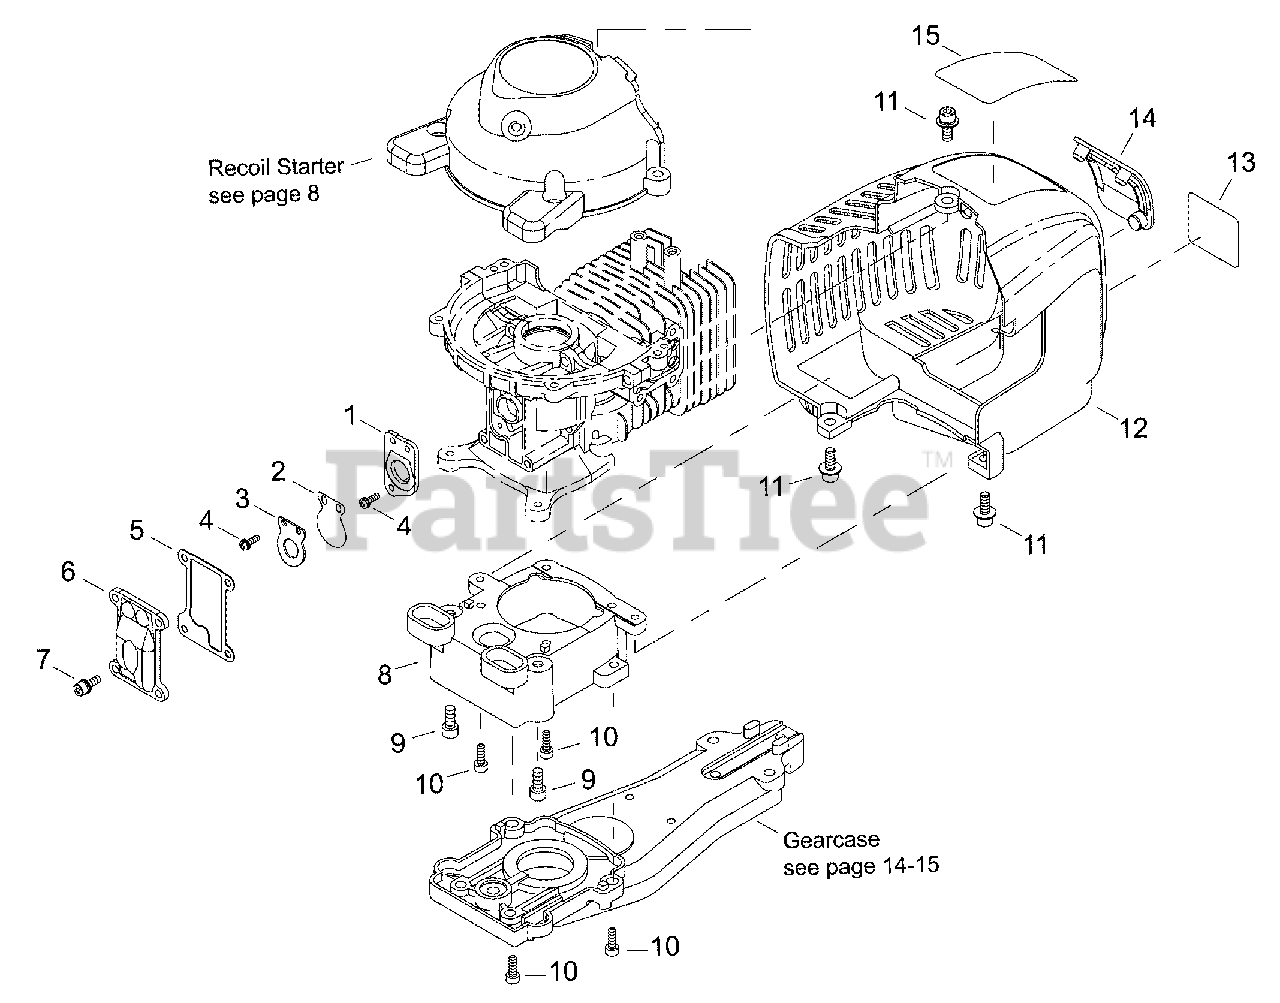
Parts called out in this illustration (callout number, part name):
1	PLATE, REED BACKING
2	VALVE, REED
3	STOP, REED VALVE
4	SCREW - 3X10
5	GASKET, REED VALVE
6	COVER, REED VALVE
7	SCREW - 4X12
8	ADAPTOR, GEAR CASE
9	SCREW - 5X12
10	SCREW - 4X12
11	SCREW - 5X14
12	COVER, ENGINE
13	LABEL - MODEL HT3000
14	COVER, SPARK PLUG
15	LABEL - E4
